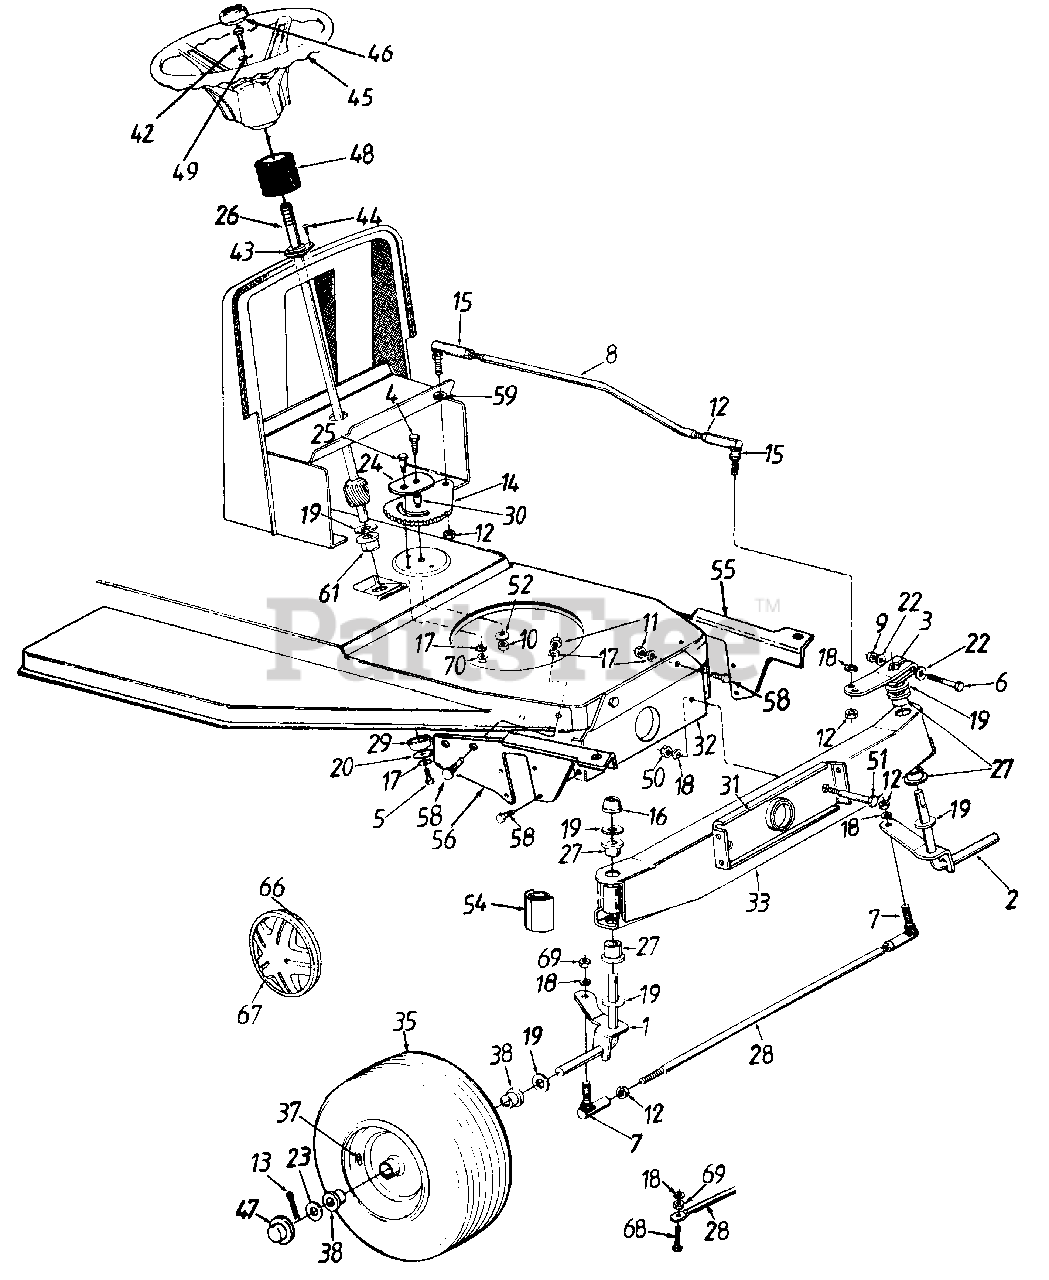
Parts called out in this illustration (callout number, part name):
1	Front Axle Ass'y. - R. H.
2	Front Axle Ass'y. - L. H.
3	Steering Arm
4	Hex Bolt 3/8-24 x 1" Lg.
5	Hex Bolt 5/16-18 x .62" (Spec.)
6	Hex Bolt 5/16-24 x 2" Lg.
7	Ball Joint 3/8-24 Thd.
8	Steering Drag Link
9	Hex Lock Nut 5/16-24 Thd.
10	Hex Nut 3/8-24 Thd.
11	Hex Nut 5/16-18 Thd. (Gr. 5)
12	Hex Jam Nut 3/8-24 Thd.
13	Cotter Pin 1/8 Dia.
14	Steering Gear Segment
15	Drag Link Ball Joint 3/8-24 Thd.
16	Push Cap
17	Lock Washer 5/16" I.D.
18	Lock Washer 3/8" I.D.
19	Fl-Washer .64" I.D. x 1.24"
20	Fl-Washer .340" I.D. x 1.125"
22	Spring Washer .32" I.D. x .62"
23	Fl-Washer .635" I.D. x 1.585"
24	Retainer Plate
25	Shld. Bolt .437" Dia. x .350"
26	Steering Shaft
27	Hex Flange Brg. .632" I.D.
28	Tie Rod
29	Spacer .985" I.D.
30	Spacer .380" I.D.
37	Air Valve
38	Bearing
42	Hex Lock Bolt 5/16-18 x 1" Lg. (Gr. 5)
43	Steering Column Brg.
44	Cr-Sunk Scr. #10 x 5/8" Lg.
45	Steering Wheel
46	Steering Wheel Cap (Round)
47	Hub Cap
48	Bellow Steering Column
49	Bell-Washer .345" I.D. x .88"
50	Flanged Lock Nut 3/8-16 Thd.
51	Shld. Bolt 1/2" Dia. x 2.04"
52	Bell-Washer .39" x 1.38" O.D.
54	Axle Cap
59	Lock Washer 3/8" I.D. (H.D.)
61	Hex Flange Bearing .634" Dia.
66	Spring Clip
67	Hub Cap (Beige)
68	Hex Bolt 3/8-24 x 1.5" Lg.
69	Hex Nut 3/8-24 Thd.
70	Lock Nut 5/16-18 Thd.
